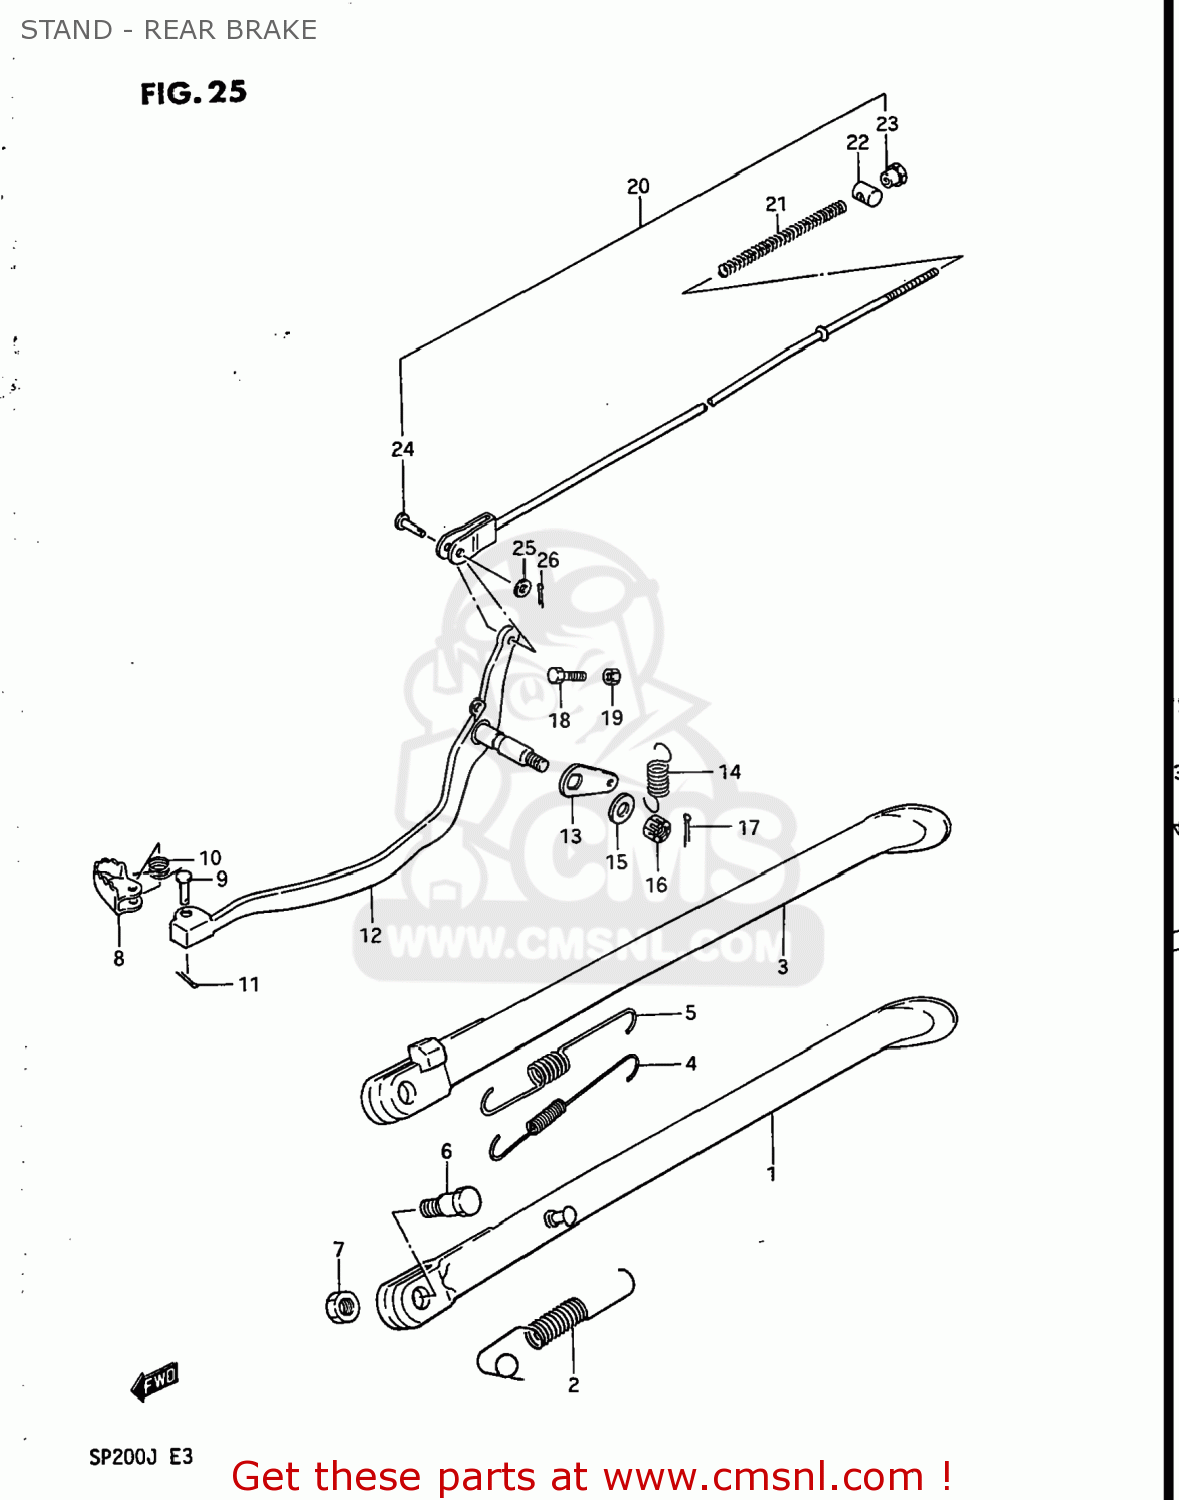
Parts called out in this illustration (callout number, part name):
1	STAND,PROP
2	SPRING
3	STAND,PROP
4	SPRING
5	SPRING
6	BOLT L:30
7	NUT
8	PEDAL,BRAKE
9	PIN
10	SPRING
11	PIN
12	ARM,BRAKE PEDAL
13	ARM,BRAKE RETURN SPRING
14	SPRING
15	WASHER
16	NUT 8MM
17	PIN 20X20
18	BOLT(6X23)
19	NUT 6MM
20	ROD ASSEMBLY,REAR BRAKE
21	SPRING
22	PIN
23	NUT (6MM)
24	PIN(L:13.5)
25	WASHER
26	PIN 20X20
